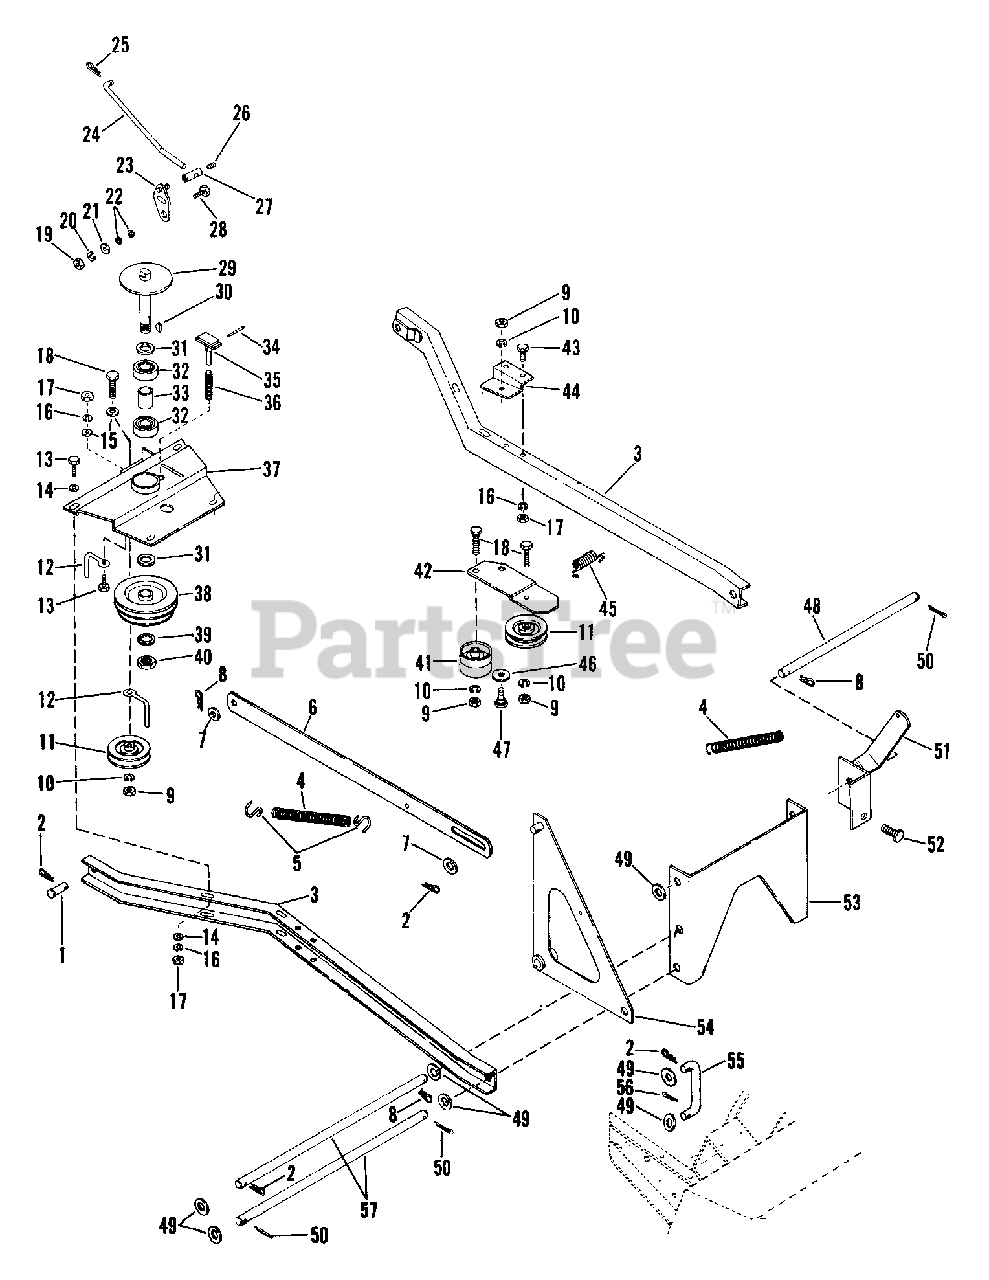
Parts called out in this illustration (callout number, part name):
1	PIN-CLEV .494X1.25 YWZC
2	PIN-HAIR INT .09X.188 PL
3	CHANNEL
4	SG-TENS .187X1.50X9.94 WLD 40
6	LIFT STRAP
7	WSHR-FL-STL .531X1.062X.095 PL
8	PIN-HAIR INT .14X.4X2.75
9	NUT-HEX .375-16
10	WSHR-LK .375X.115 HVY PL
11	IDLER-V 3.06 X .38
12	BELT FINGER
13	BLT-HEX .31-18X1.00 PL GR 2
14	WSHR-FL-STL .323X.625X.062 PL
15	WSHR-FL-STL .38X.875X.083 PL
16	WSHR-LK .312X.097 PL HVY
17	NUT-HEX .312-18
18	BLT-HEX .38-16X1.75 PL GR2
19	NUT-HEX .250-20 PL
20	WSHR-LK .250X.077 HVY PL
21	WSHR-FL-STL.312X.734X.065PL
22	WSHR-FL-STL .265X.500X.087 PL
23	BRAKE ACTUATOR
24	BRAKE ROD
25	PIN-HAIR INT .08X.18X1.18
26	SCR-SET .32-18X.38 SKHCUPNL OH
27	ROD ADAPTER
28	BLT-HEX .25-20X.75 PL GR5
29	SPINDLE SHAFT
30	KEY-WDRF .188X.75X.313 SAE 9
31	WSHR-FL-STL .781X1.250X.059 PL
32	BRG-BALL .750X1.781X.61
33	SPACER .765X1.000X1.252
34	PIN-ROLL .188X1.75
35	BRAKE PLUNGER
36	SG-COMP ??X.44X?? WLD 10
37	SPINDLE HOUSING
38	DOUBLE SHEAVE
39	WSHR-LK-INT .750X.050 MED
40	NUT-JAM .75-10 PL
41	IDLER-FLAT 2.25 X .38
42	IDLER ARM
43	BLT-HEX .31-18X.75 PL GR5
44	IDLER MOUNT
45	SG-TENS .080X.73X3.06 WLD 20
46	WSHR-FL-STL .511X1.441X.125 PL
47	SHOULDER BOLT .50 X .281
48	MOUNT ROD
49	WSHR-FL-STL.656X1.312X.095 PL
50	PIN-COTR .15X1.50
51	SPRING ANCHOR
52	BLT-HEX .50-13X1.25 PL GR2
53	PIVOT SUPPORT
54	LIFT BELLCRANK
55	LIFT LINK
56	PIN-COTR .12X1.0 PL
57	PIVOT ROD
